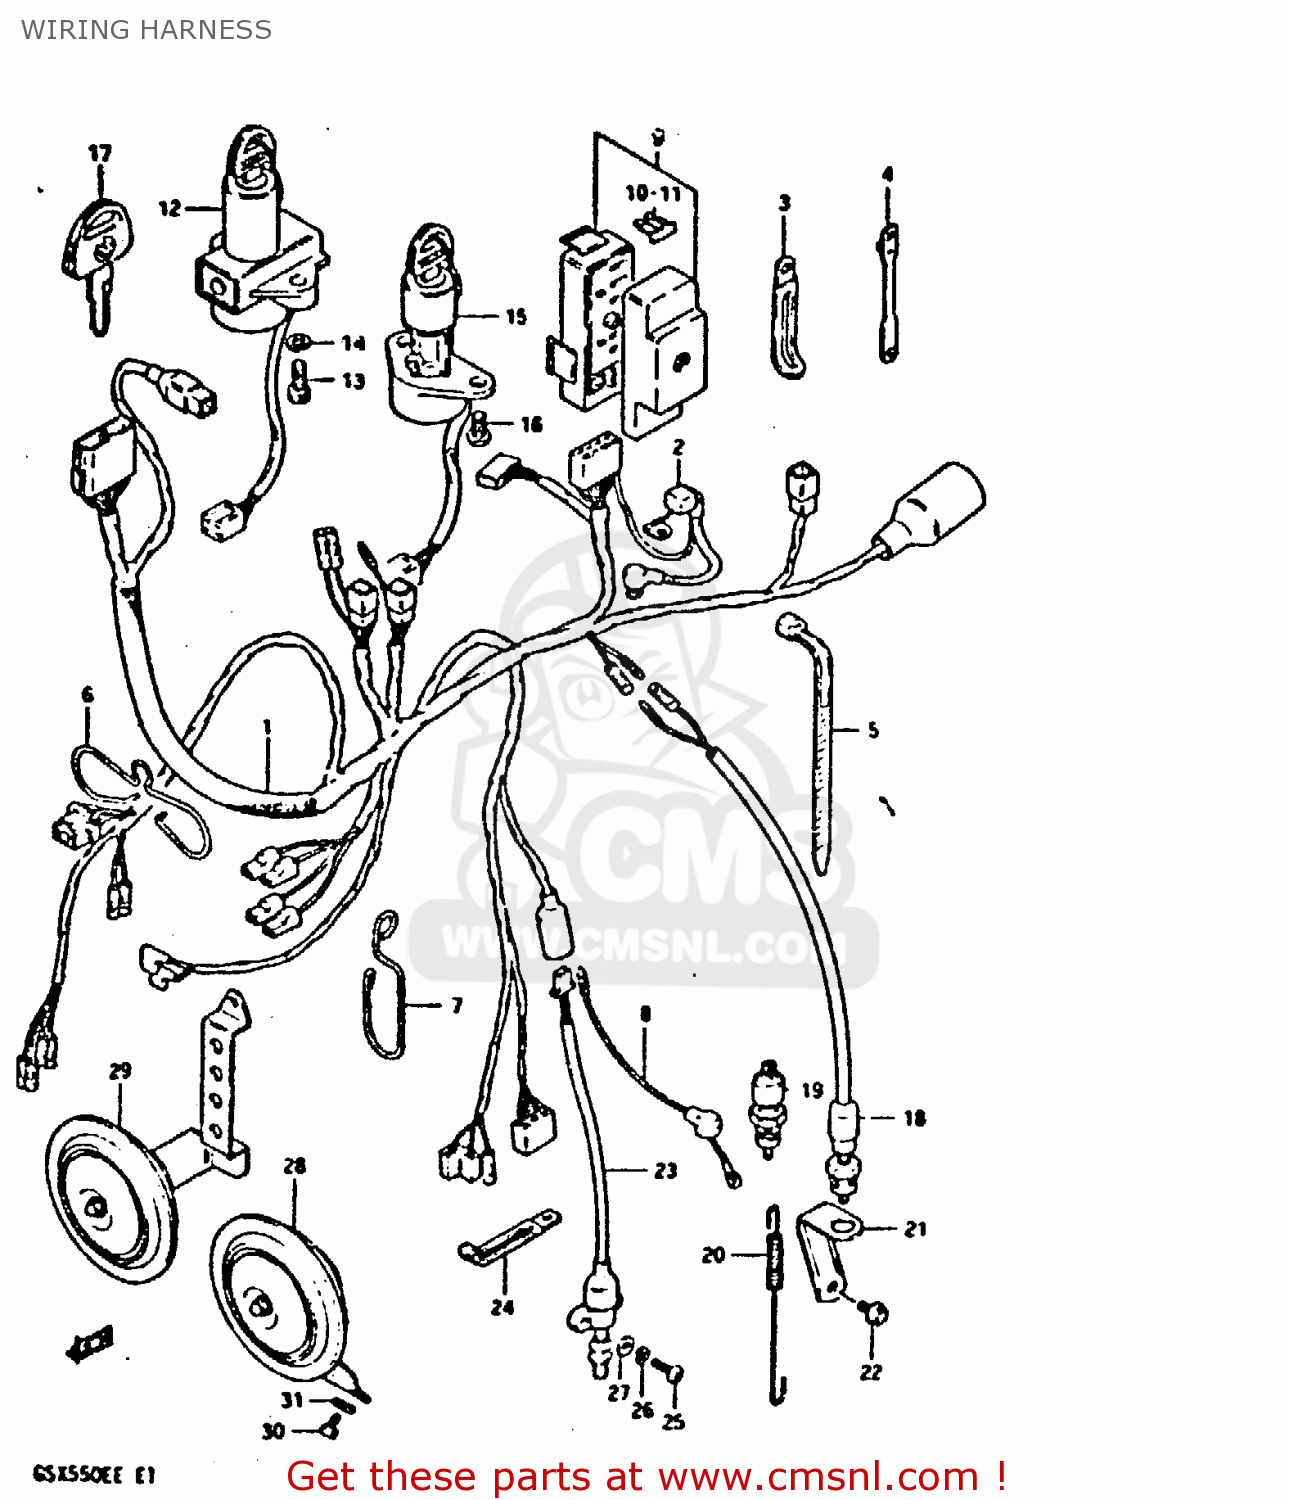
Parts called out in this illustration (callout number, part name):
1	HARNESS,WIRING
2	CAP,BATTERY PLUS TERMINAL
3	CLAMP
4	CLAMP,L:88
5	CLAMP(L:95)
6	BOOT,WIRING HARNESS
7	GUIDE,WIRING HARNESS
8	WIRE
9	FUSE BOX ASSY
10	FUSE(10A)
11	FUSE(15A)
12	SWITCH ASSY, IGNITION
13	BOLT
14	LOCK WASHER
17	KEY,BLANK
18	SWITCH ASSY,STOP LAMP
19	SWITCH ASSEMBLY,STOP LAMP
20	SPRING
21	BRACKET,BRAKE LAMP SWITCH
22	BOLT
23	SWITCH ASSEMBLY,SIDE STAND
24	CLAMP
25	SCREW 5X20
26	WASHER,LOCK
27	WASHER,5MM
28	HORN ASSEMBLY
29	HORN ASSEMBLY
30	BOLT
31	WASHER, LOWER
